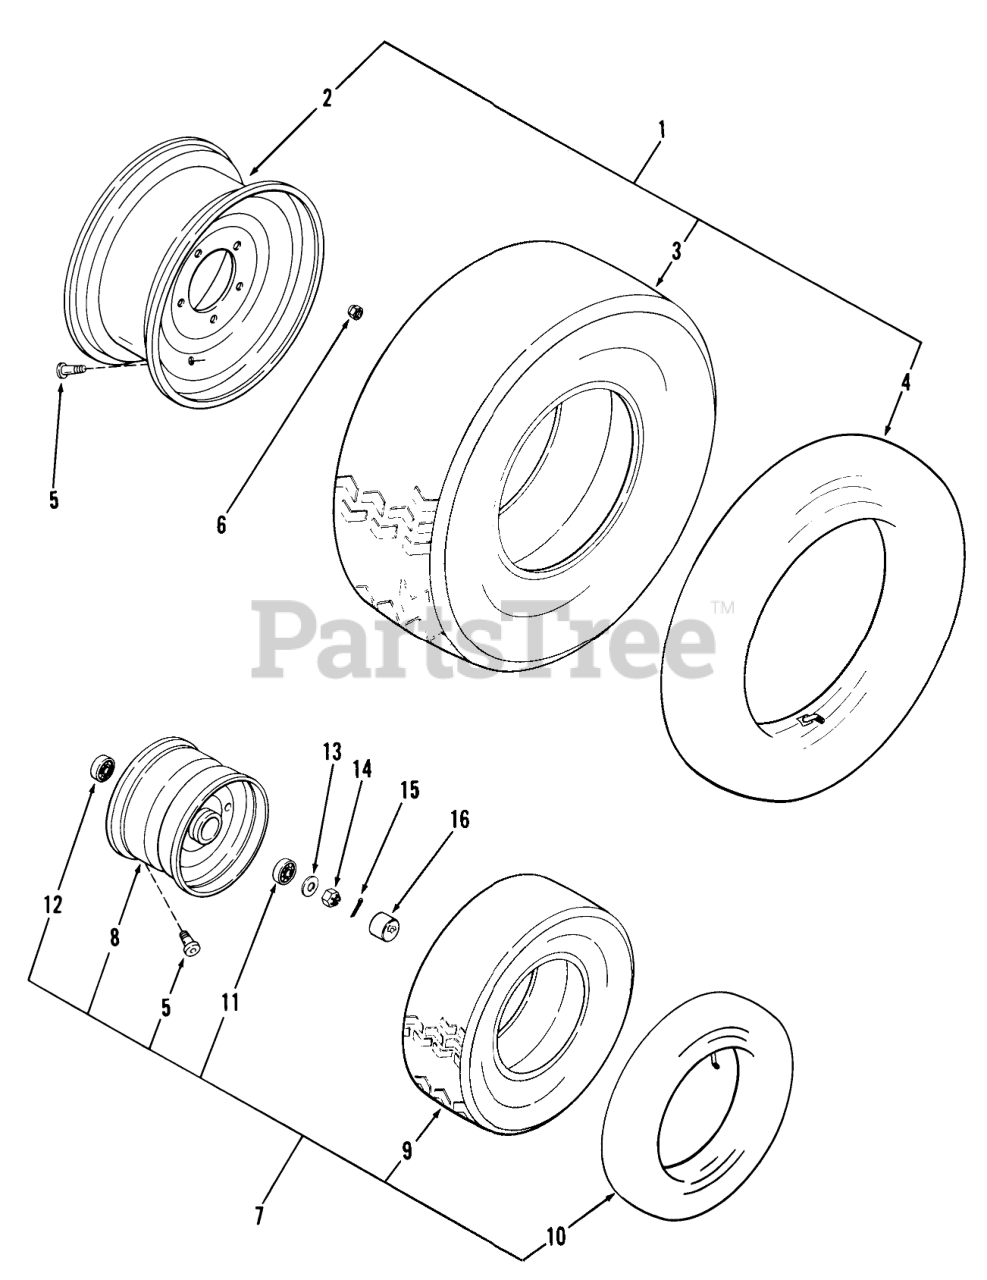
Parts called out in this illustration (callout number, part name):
4	Yoke
5	VALVE
10	TUBE-TIRE
